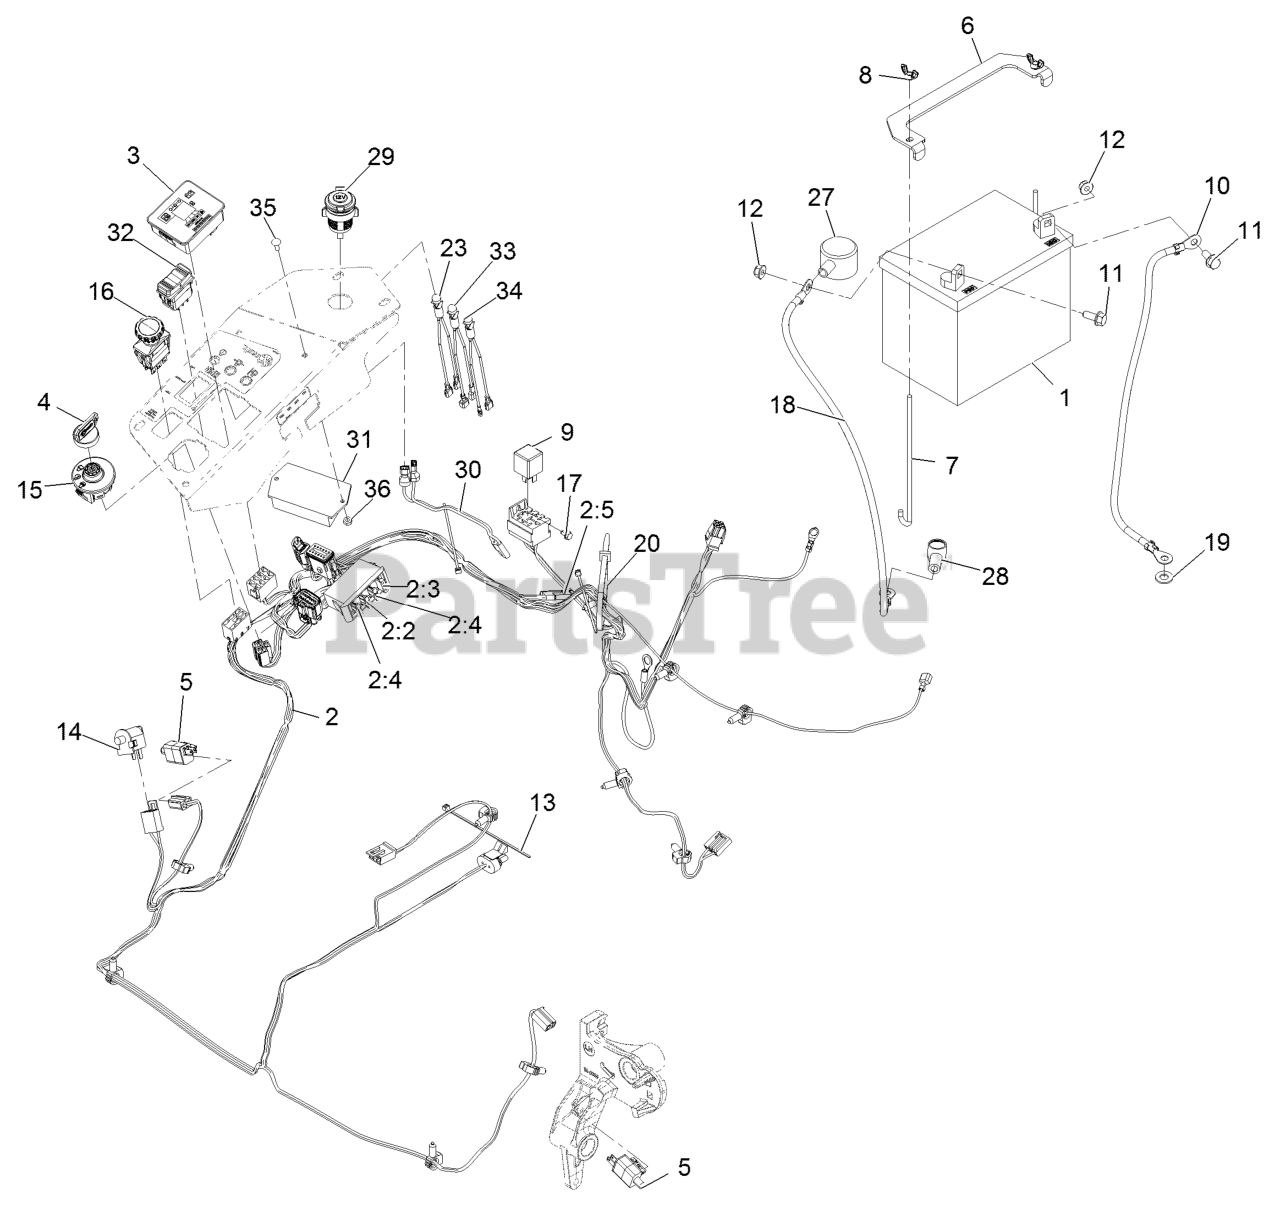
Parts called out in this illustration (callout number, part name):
1	Battery-Wet
2	HARNESS-WIRE
2:2	FUSE-BLADE, 10 AMP
2:3	FUSE-BLADE, 15 AMP
2:4	FUSE-BLADE, 25 AMP
2:5	CAP-PLUG
3	FUEL/HOUR METER ASM
4	KEYS-IGNITION (SPARE PAIR
4	KEY-IGNITION
6	STRAP-TIE DOWN, BATTERY
7	BOLT-HOLDDOWN
8	WINGNUT
10	CABLE-BATTERY, NEGATIVE
11	SCREW-HHF
12	NUT-HF, NI
13	TIE-CABLE
14	SWITCH-BAIL
16	SWITCH-PTO, 10 AMP
17	SCREW-HWH
18	CABLE-BATTERY, POSITIVE
19	WASHER-FLAT
20	TIE-PLASTIC
23	INDICATOR-LED, RED
27	INSULATOR-BATTERY
28	INSULATOR-SOLENOID
29	RECEPTACLE-12V
30	HARNESS, RECEPTACLE 12V
31	CONTROLLER-RED
32	SWITCH-ROCKER
33	LIGHT-LED, RED
34	LIGHT-LED, RED
35	SCREW-CARR
36	NUT-LOCK, NI
